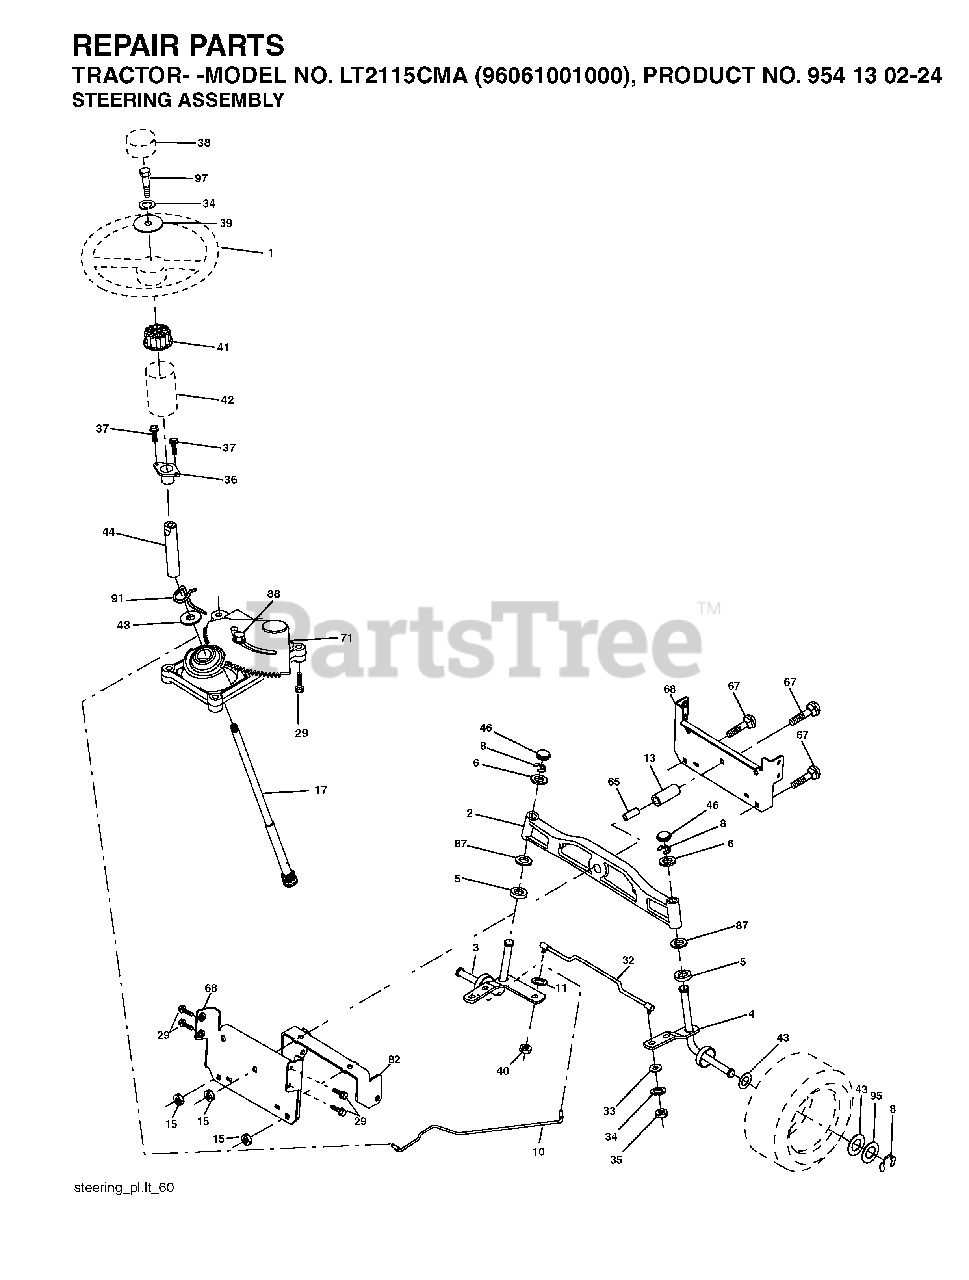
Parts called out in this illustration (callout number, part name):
1	WHEEL.STEERING.PREM.2.BLK
2	AXLE ASSY FRONT
3	SPINDLE.ASM.LH.15"TIRES
4	SPINDLE.ASM.RH.15"TIRES
8	RING CLIP
10	DRAGLINK.15".TIRES.2001
11	WASHER, LOCK 3/8
13	TUBE, PIVOT AXLE
15	NUT
17	SHAFT STEERING SPLINE
29	SCREW, 3/8-16X3/4
32	ROD.ASM.TIE.BALL.JOINT.NOVAN
33	WASHER M
34	LOCKWASHER
35	NUT, CROWNLOCK
36	BUSHING, STEERING
38	INSERT.CAP.STRG.WH.BLACK
39	WASHER.11/32
40	NUT CROWNLOCK 3/8-24
41	ADAPTER, WHEEL STNG..
42	BOOT.STEERING.SHAFT.BLACK
44	SHAFT.EXTEN.STRG.SPLINE
46	CAP.SPINDLE
65	SPACER BRACE AXLE
67	BOLT CARRIAGE
68	BRACE.AXLE.15"TIRES
71	STEERING ASM
82	BRACKET
87	WASHER, FLAT .781 X 1 1/2"
88	BOLT, SHOULDER 7/16-20
91	CLIP.STEERING
95	WASHER.HARDENED
